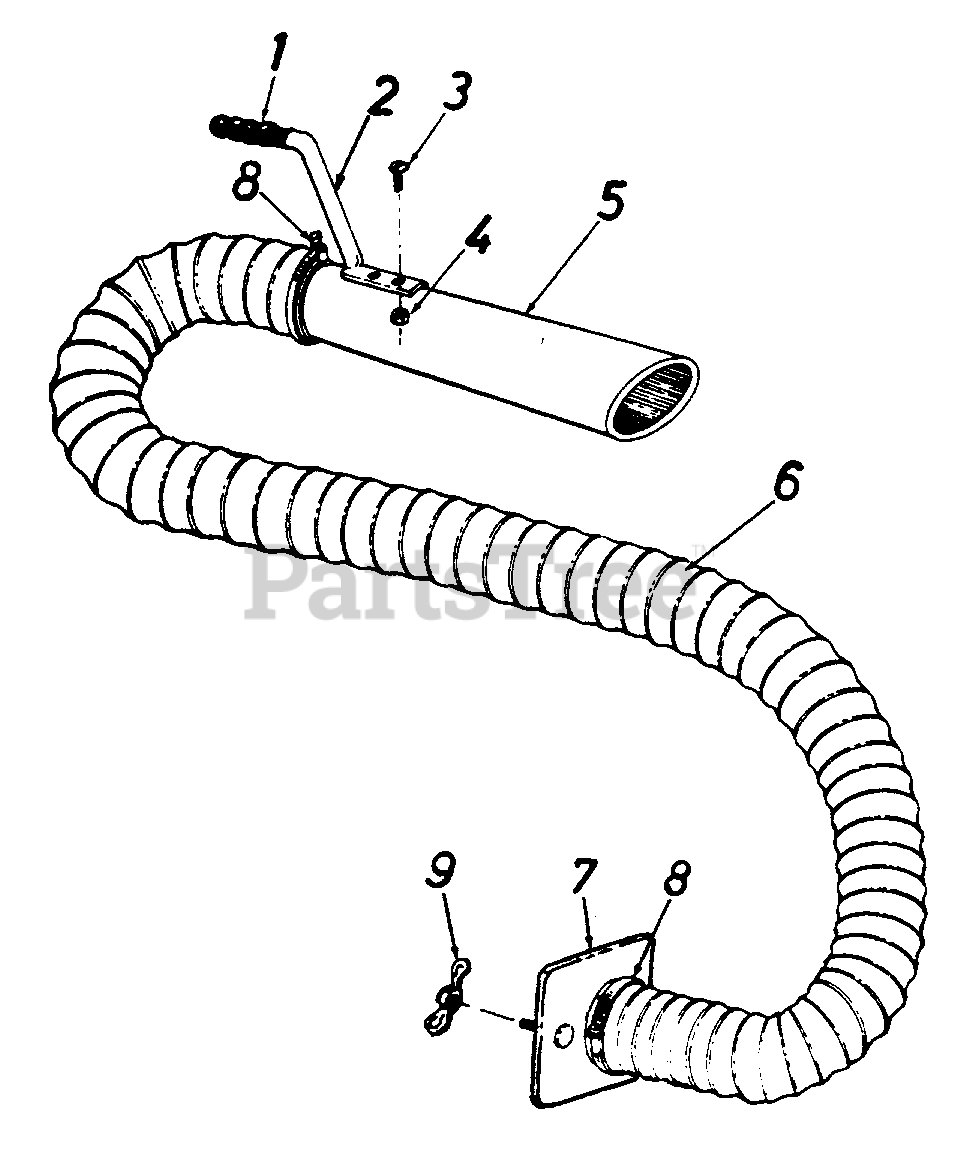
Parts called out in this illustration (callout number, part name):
1	Handle Grip
4	Hex Nut 10-24 Thd.
5	Hose Nozzle
6	Flexible Hose 4" Dia. x 10'
7	Hose Adapter Plate
8	Hose Clamp - 4"
9	Wing Nut 1/4-20 Thd.
